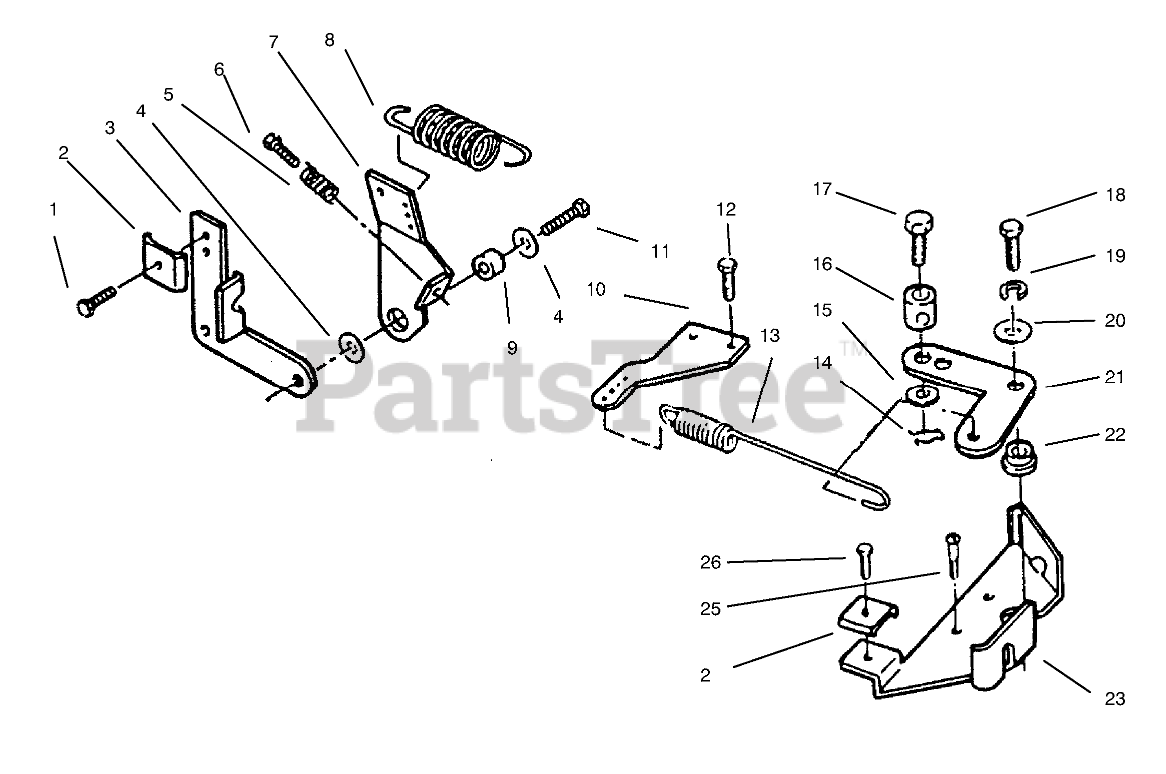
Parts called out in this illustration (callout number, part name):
1	SCREW-TAPPING
3	BRACKET
4	WASHER-FLAT
5	SPRING
6	SCREW-TAP
7	GOVERNOR CONTROL ARM
8	SPRING
9	BUSHING
10	ADAPTER-GOV ARM
11	SCREW-HWH
12	Screw
13	SPRING-GOV
14	PIN-COTTER
15	WASHER-FLAT
16	BUSHING
17	SCREW
18	SCREW - CAP HEX HEAD
19	WASHER-LOCK, SPRING
20	WASHER-FLAT
21	Governor Control Arm
22	BUSHING-GOV CONTROL
23	BRKT-GOVERNOR CONTRL
25	HEX HD CAP SCREW
26	TAPPING HEX HD CS
